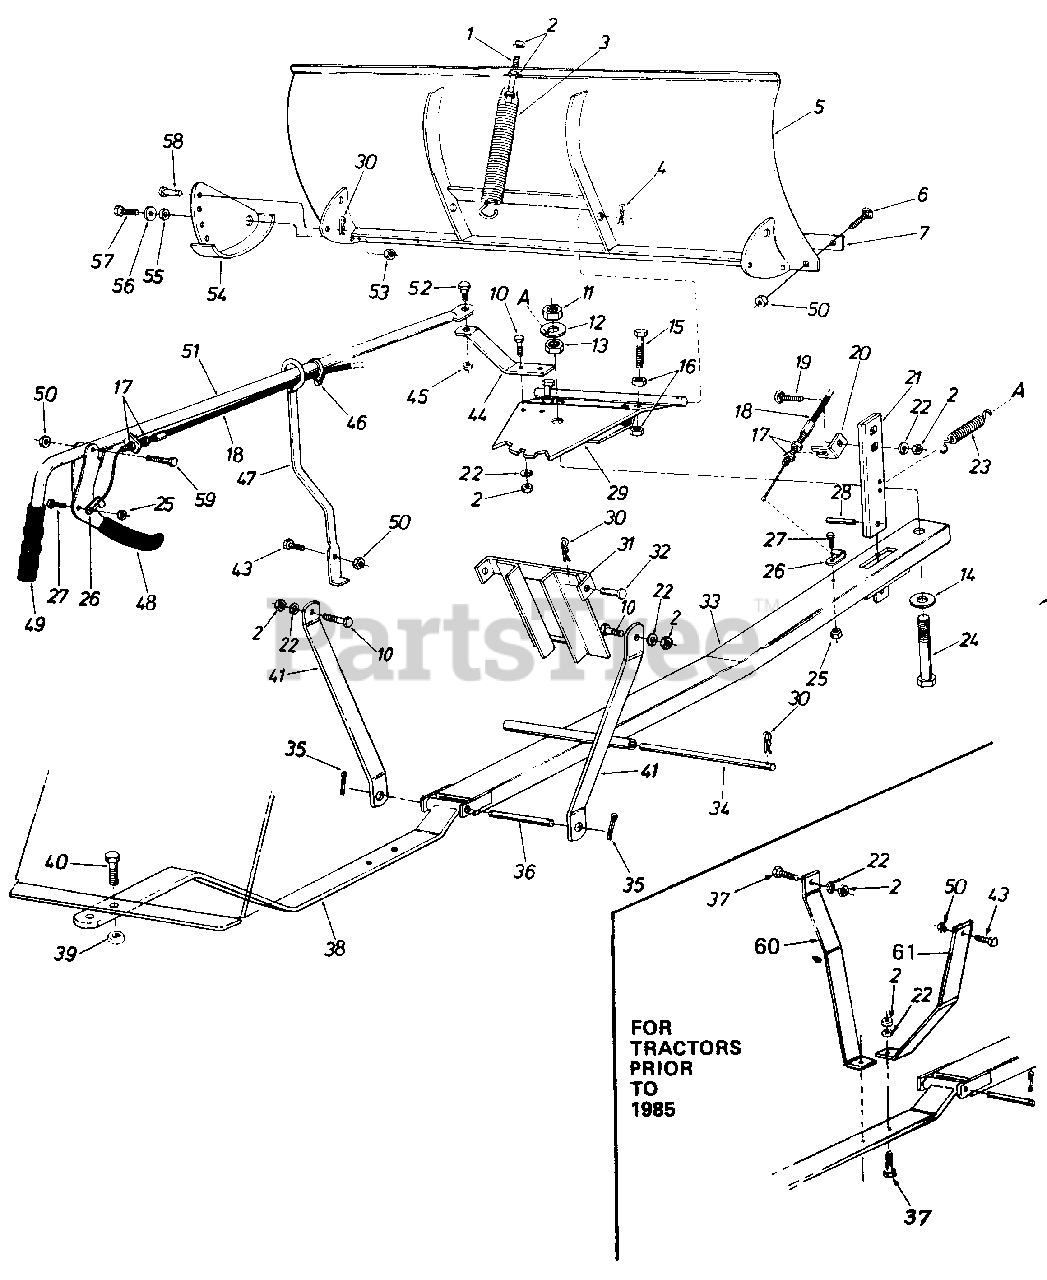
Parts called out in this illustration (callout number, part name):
1	Hex Scr. 3/8-16 x 4.50" Lg.*
2	HexNut 3/8-16 Thd.*
3	Blade AdjustmentSpring
4	Hairpin Clip 5/32"Dia.
5	48" Blade Ass'y.
6	Carriage Bolt 5/16-18 x .75" Lg.*
7	Wear Plate 48"
10	Hex Scr. 3/8-16 x 1..00" 4*
11	Hex L.-Nut 3/4-10Thd.
12	Fl.-Wash. .810" I.D. x 2.00" O.D.
13	Hex Jam Nut 3/4-10Thd.*
14	Fl.-Wash. .810" I.D. x 2.00" O.D.
15	Hex Scr. 1/2-13 x 2.00" Lg.*
16	Hex Nut 1/2-13Thd.*
17	Hex Jam Nut 5/16- 0 0 24 Thd.*
18	Control Cable Ass'y.
19	Carriage Bolt 3/8-16 x 1.25" Lg.*
20	Cable Guide Bracket
21	Angle - Lock Bar
22	L.-Wash. 3/8" I.D.
23	Angle Lock Spring
24	Hex Scr. 3/4-10 x 4.00" Lg.
25	Hex L.-Nut1/4-20 Thd.
26	Clevis Lanyard Fitting
27	Hex Scr. 1/4-20 x .75" 4.
28	Roll Pin 1/4" Dia. x 1.00"
29	Pivot Plate Ass'y.
30	Hairpin Clip 3/32" Dia.
31	Guide Bracket Ass'y.
32	Clevis Pin 1 2" Dia. x 1.00" Lg.
33	Push Bar Ass'y.
34	Lift Shaft
35	Cotter Pin 5/32" Dia. x 1.00" Lg.
36	Pivot Shaft
37	Hex Scr. 3/8-16 x 1.25" 4*
38	Hanger Bracket Ass'y. N
39	Hex L.-Nut 5/8-11 Thd
40	Hex Scr. 5/8-11 x 1.50" Lg.*
41	Hanger Link
43	Hex Bolt 5/16-18 x 1.00" Lg.
44	Blade Pivot Bracket
45	Hex L.-Nut 0 0 3/8-16 Thd.
46	Nylon Cable Tie
47	Tube Guide Ass'y.
48	Clutch Grip Ass'y.
49	Grip-3/4" Handle
50	Hex L-Nut 0 0 5/16-18 Thd.
51	Tube Handle Ass'y.
52	Shld. Scr.-Special 3/8-16 Thd.
53	Hex L.-Nut 3/8-16 Thd.
54	Skid Assembly
55	Spacer
56	Fl.-Wash. .385" I.D. x 1.00" O.D.
57	Hex Scr. 3/8-16 x4 .75" Lg.*
58	Clevis Pin 5/16" Dia. x .75" Lg.
59	Hex Scr. 5/16-18 x 1.50"Lg.
60	Mounting Brkt.-L.H.
61	Mounting Brkt-R.H.
